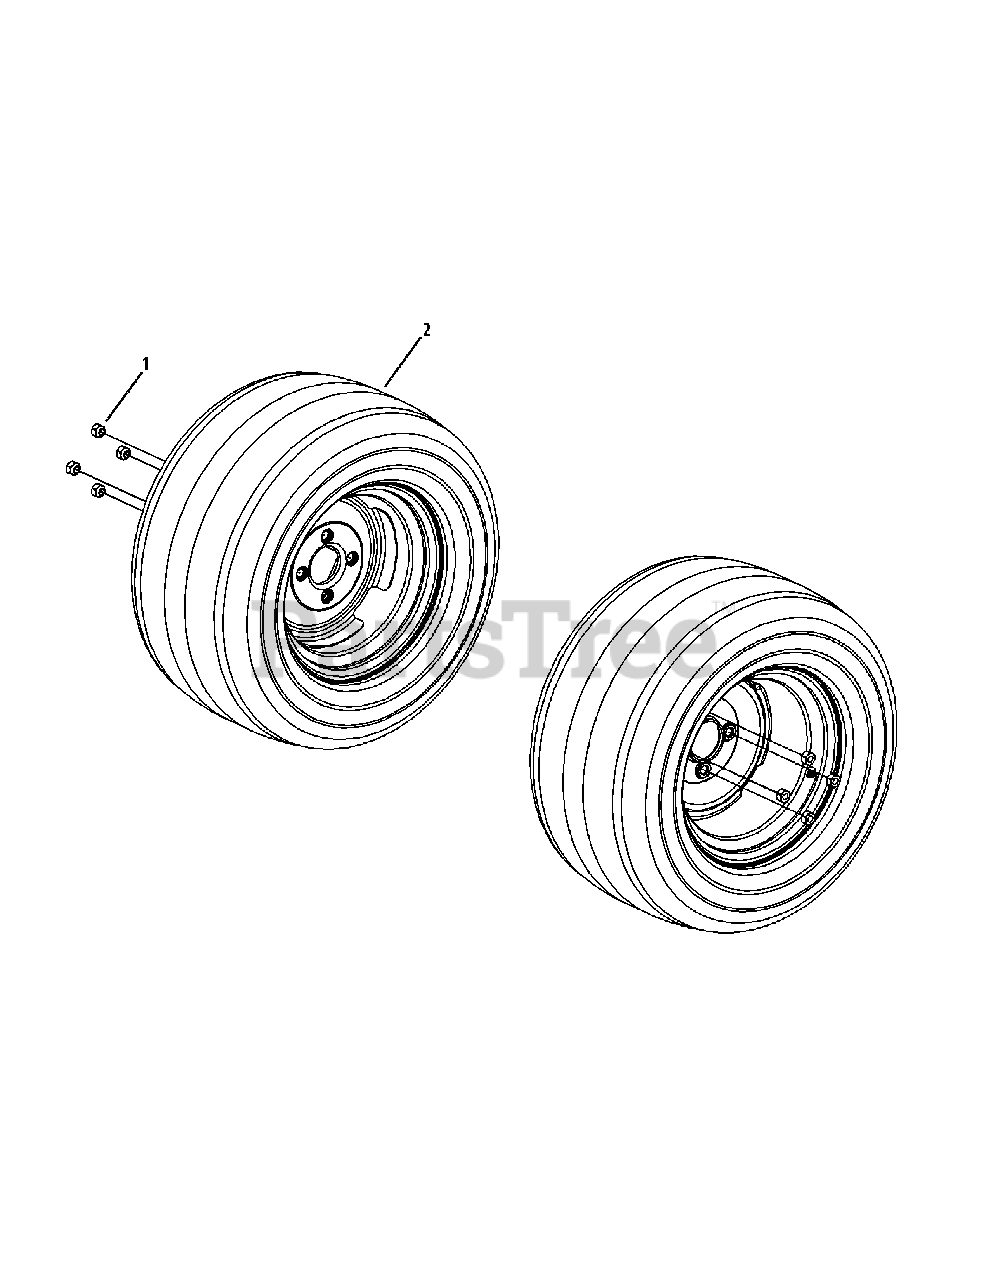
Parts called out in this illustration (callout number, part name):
1	Lug Nut, 1/2-20
2	Wheel Assembly, 9.5-12, Beige
2	Tire, 9.5-12
2	Wheel Assembly, 24 x12-12, Beige
2	Tire, 24 x 12-12
2	Wheel Assembly, 24 x 12-12, Turf Saver
2	Tire, 24 x 12-12, Turf Saver
